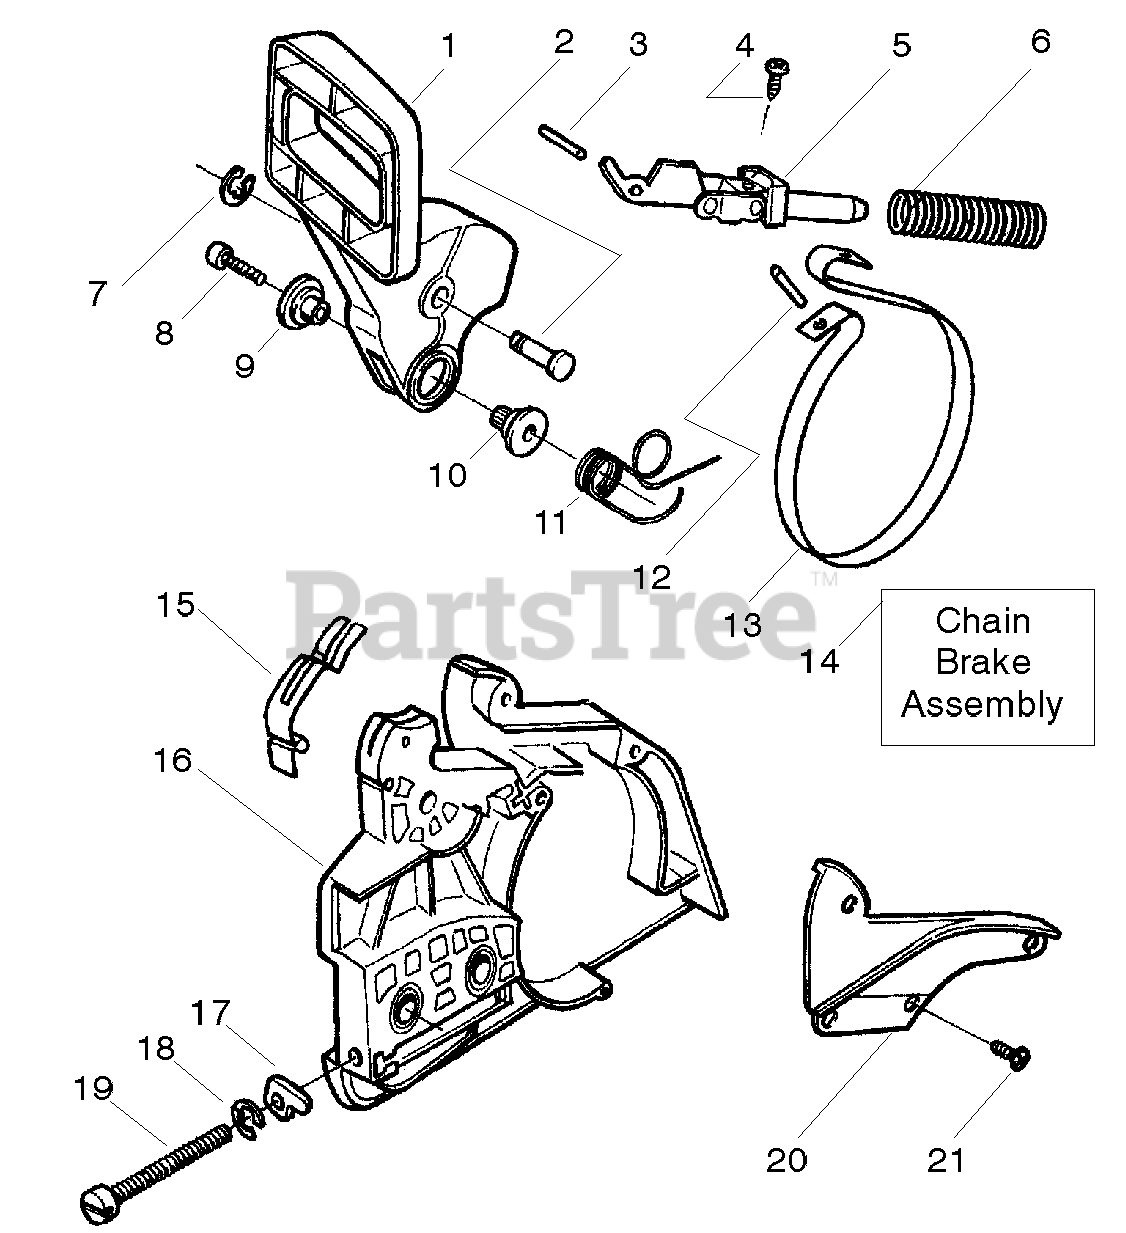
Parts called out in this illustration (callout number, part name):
1	HANDGUARD
4	SCREW
5	FRONT LINK ASSY
6	%COMPRESSION SPRING
9	JOURNAL, RIGHT
10	SHAFT PIVOT
11	SPRING,BRK HDL 36/41
13	BRAKE BAND
14	CHAIN BRAKE ASM.
15	SPRING-POSITION
16	CLUTCH COVER
17	ADJUST PIN,BAR 36/41
19	BAR ADJUSTING SCREW
20	CHAIN BRAKE COVER
21	SCREW
